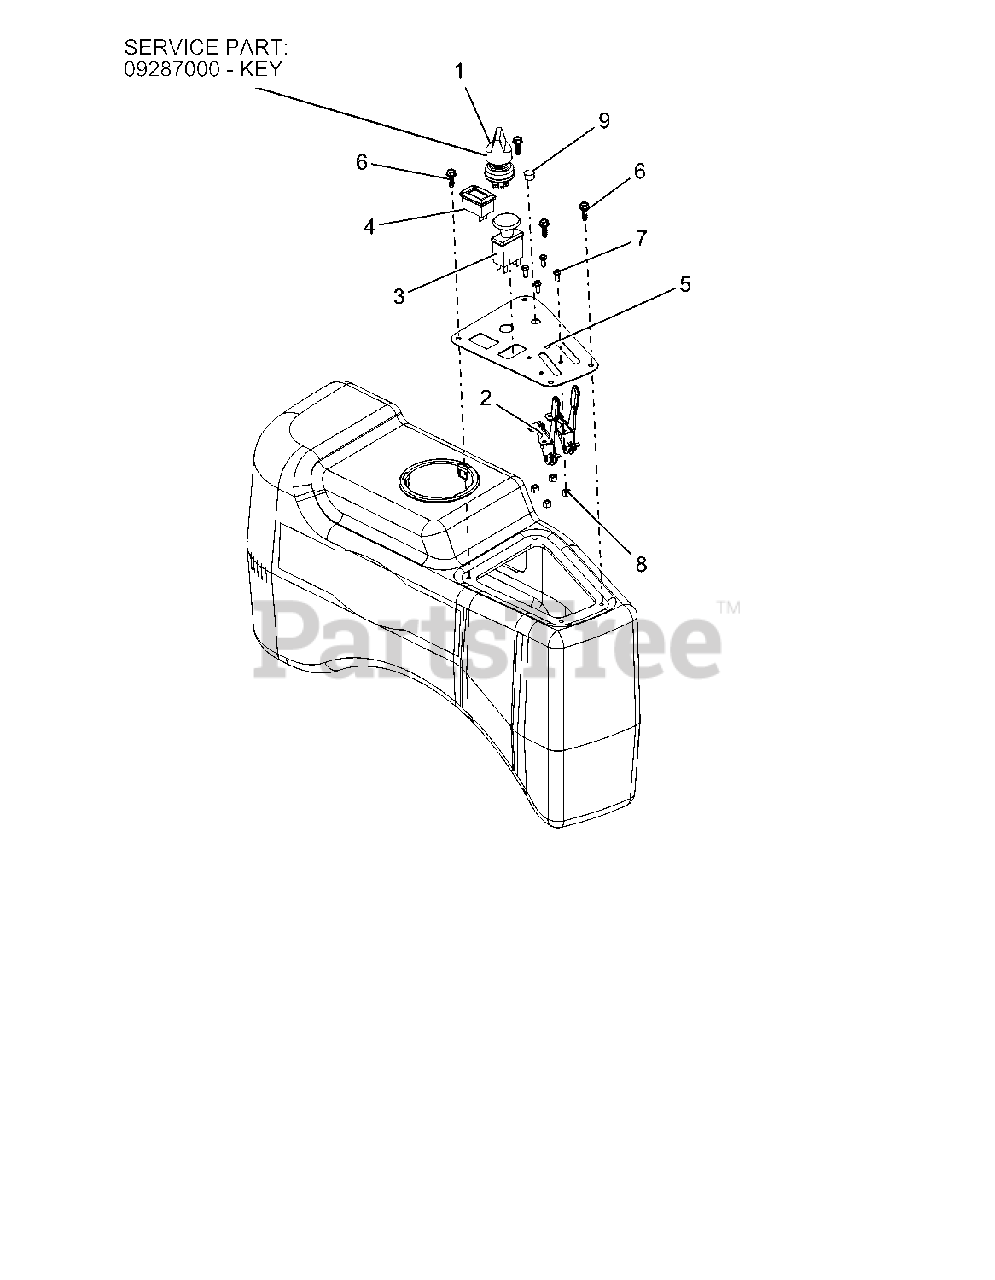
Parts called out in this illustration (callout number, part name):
1	SWITCH, IGNITION
1	KEY
2	CABLE, CONTROL
3	SWITCH, CLUTCH
4	METER, HOUR W/MAINTENANCE
5	PANEL, INSTRUMENT-BLACK
6	SCR-PLASTITE .25-10X.75 YWZC
7	@SCR-MCH 10-24X.50 HWH YWZC
8	NUT-LK-NYL #10-24 YWZC
9	PLUG, HOLE .50 DIA
